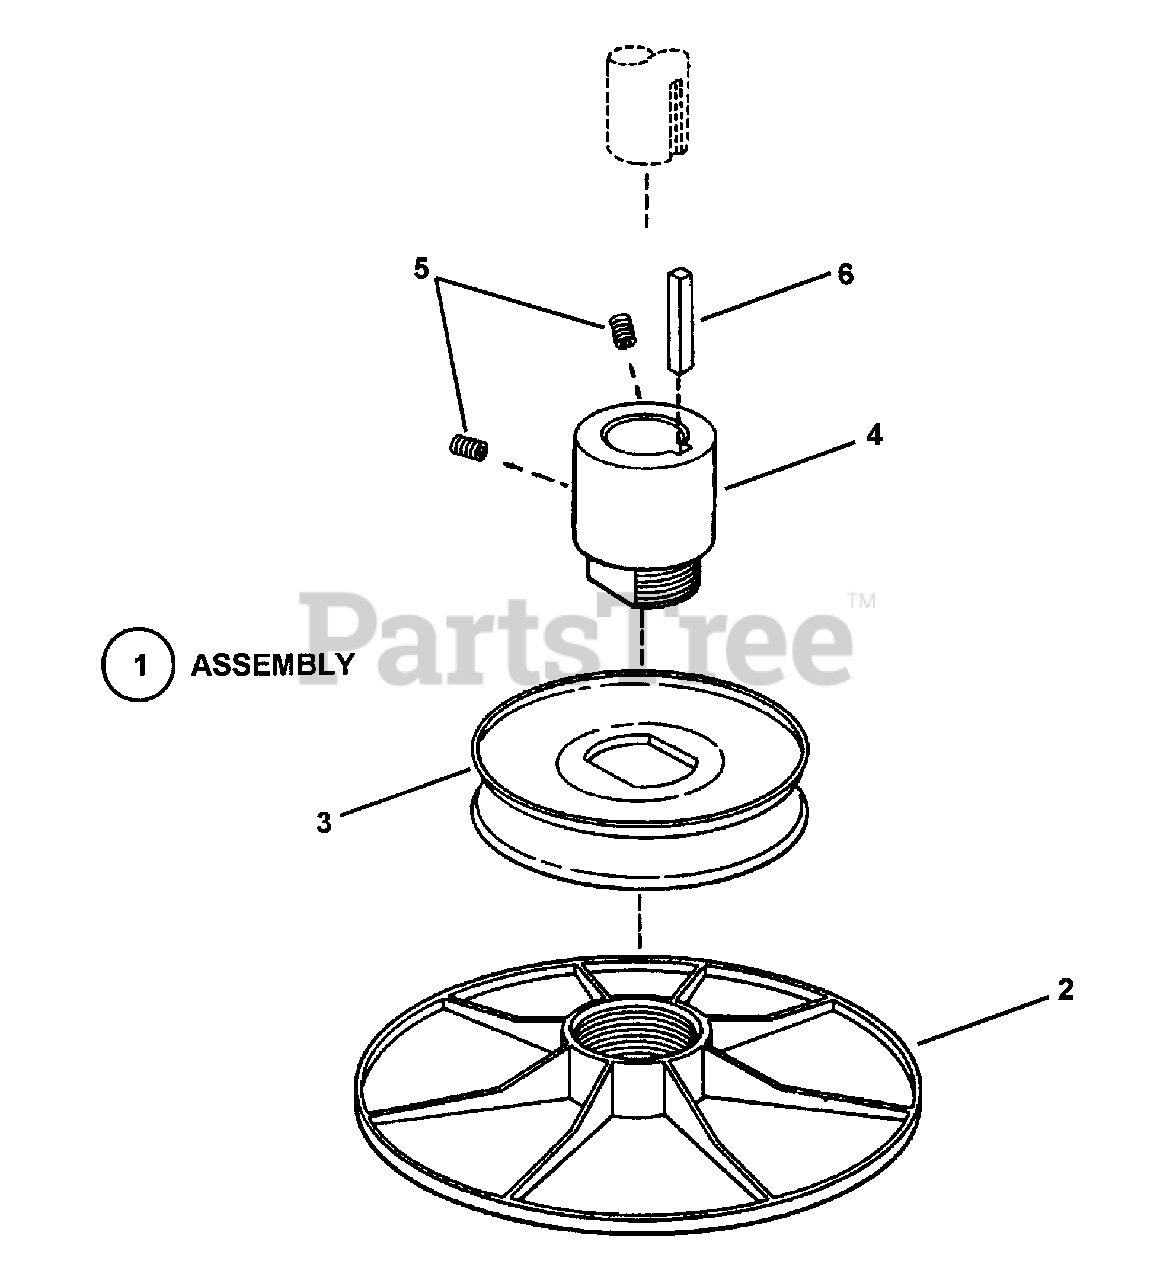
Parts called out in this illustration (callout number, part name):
1	ASSEMBLY, Drive Disc
2	DISC, Drive
3	PULLEY, 5.75" Outside Diameter
4	HUB, Drive Disc
5	SCREW, 3/8-16 x 3/8" Set
6	KEY, 1/4 x 1/4 x 2"
